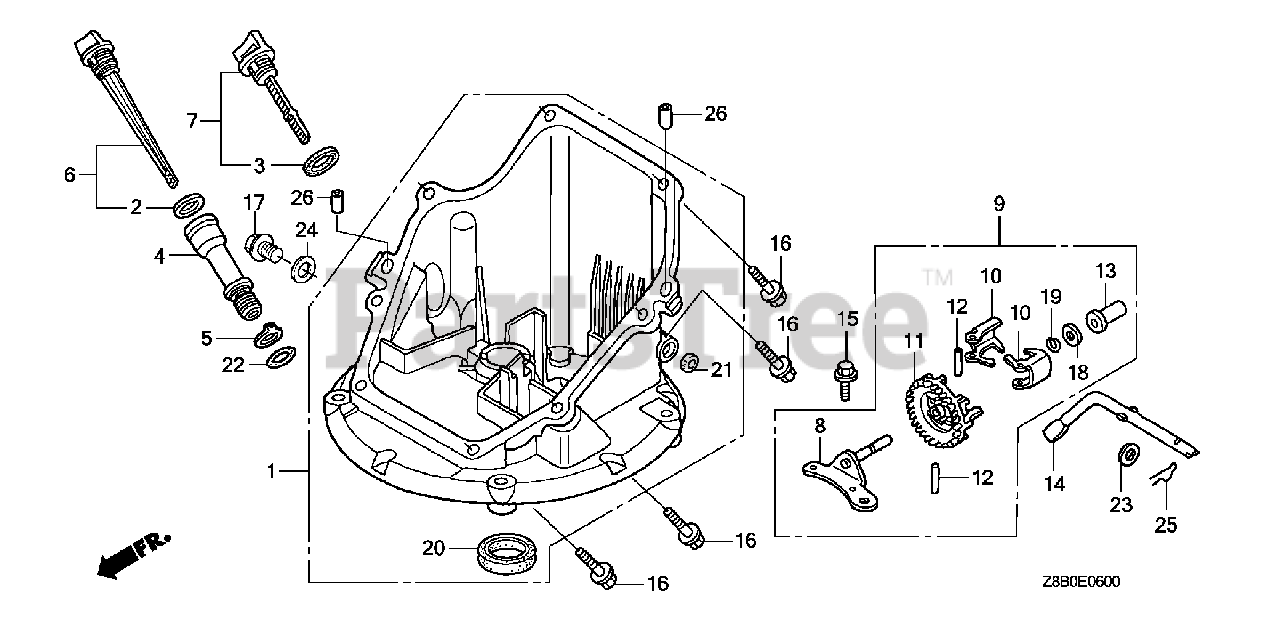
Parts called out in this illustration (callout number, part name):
1	PAN ASSY., OIL
2	GASKET, OIL FILLER CAP
4	EXTENSION, OIL FILLER
5	WASHER, EXTENSION LOCK
6	GAUGE ASSY., OIL LEVEL
8	SHAFT, GOVERNOR HOLDER
9	GOVERNOR ASSY.
10	WEIGHT, GOVERNOR
11	HOLDER, GOVERNOR WEIGHT
12	PIN, GOVERNOR WEIGHT
13	SLIDER, GOVERNOR
14	SHAFT, GOVERNOR ARM
15	BOLT, FLANGE (6X14) (CT200)
16	BOLT, FLANGE (6X25) (CT200)
18	WASHER, THRUST (6MM)
19	CLIP, GOVERNOR HOLDER
20	OIL SEAL (28X41.25X6)
22	O-RING (14.8X2.4) (NOK)
23	WASHER, PLAIN (6MM)
25	PIN, LOCK (8MM)
26	PIN, DOWEL (8X20)
